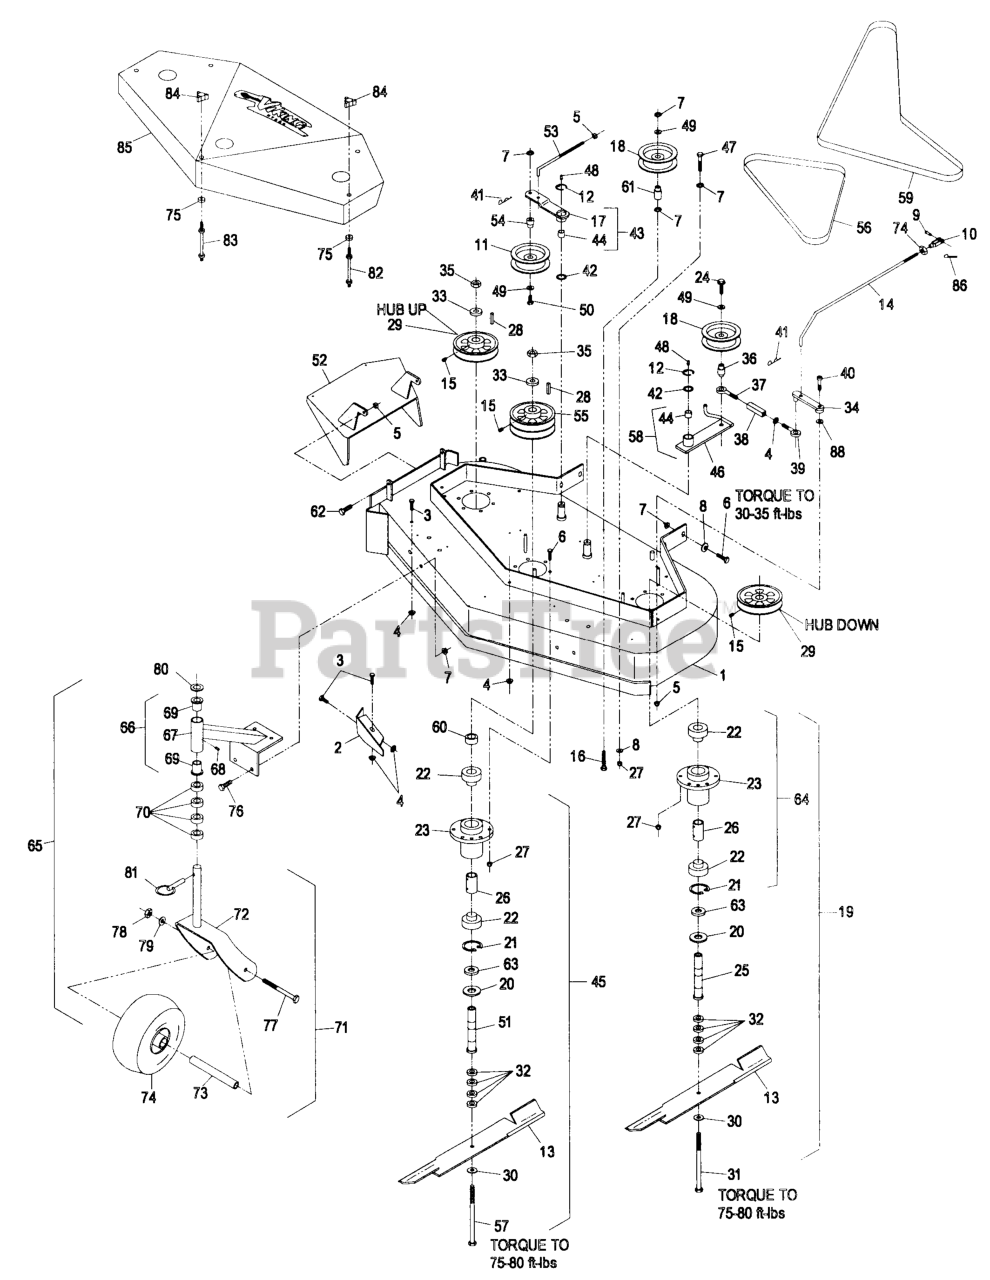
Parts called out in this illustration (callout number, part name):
2	BAFFLE-DOGLEG
9	PIN-CLEVIS
10	YOKE-ADJUSTABLE
11	IDLER,PULLEY
14	ARM-LINKAGE, ASSIST
15	SCREW-SET
16	BOLT,TAP HH3/8-16X2-1/4
17	Arm Weldmt, Rh
19	HOUSING,CUTTER COMPLETE(S
20	GUARD-BEARING, BOTTOM
22	BEARING
25	TUBE-SPINDLE, SHORT
26	SPACER-BEARING
30	WASHER-SPRING
31	SCREW-CAP, HH
33	WASHER-RETAINER, SHEAVE
36	BUSHING-ENGAGEMENT
37	EYEBOLT-THREAD, LH
38	BODY-TURNBUCKLE
39	EYEBOLT-THREAD, RH
40	BOLT,SHLDR KSKH 3/8 X 1
41	PIN-COTTER
42	WASHER-SPINDLE
43	ARM WLDMNT W/BUSHING
44	BEARING,POWDERED METAL
45	HOUSING,CUTTER COMPLETE(S
51	TUBE,SPINDLE LONG
53	LINKAGE
54	BUSHING-IDLER
56	BELT,FRONT DECK
57	SCRW,CAP HH 5/8-18X8.5
59	BELT,BLADE DRIVE 36
60	SPACER,SHEAVE/BEARING
61	BUSHING,IDLER
63	SPACER-PULLEY/BEARING
65	CASTER/MOUNT ASM
66	SUPPORT ASM
69	BEARING-FLANGED
70	SPACER-CASTER
80	WASHER-FLAT
82	STUD-SHIELD, BELT (SHORT)
83	STUD-SHIELD, BELT (LONG)
84	KNOB-3 PRONG
